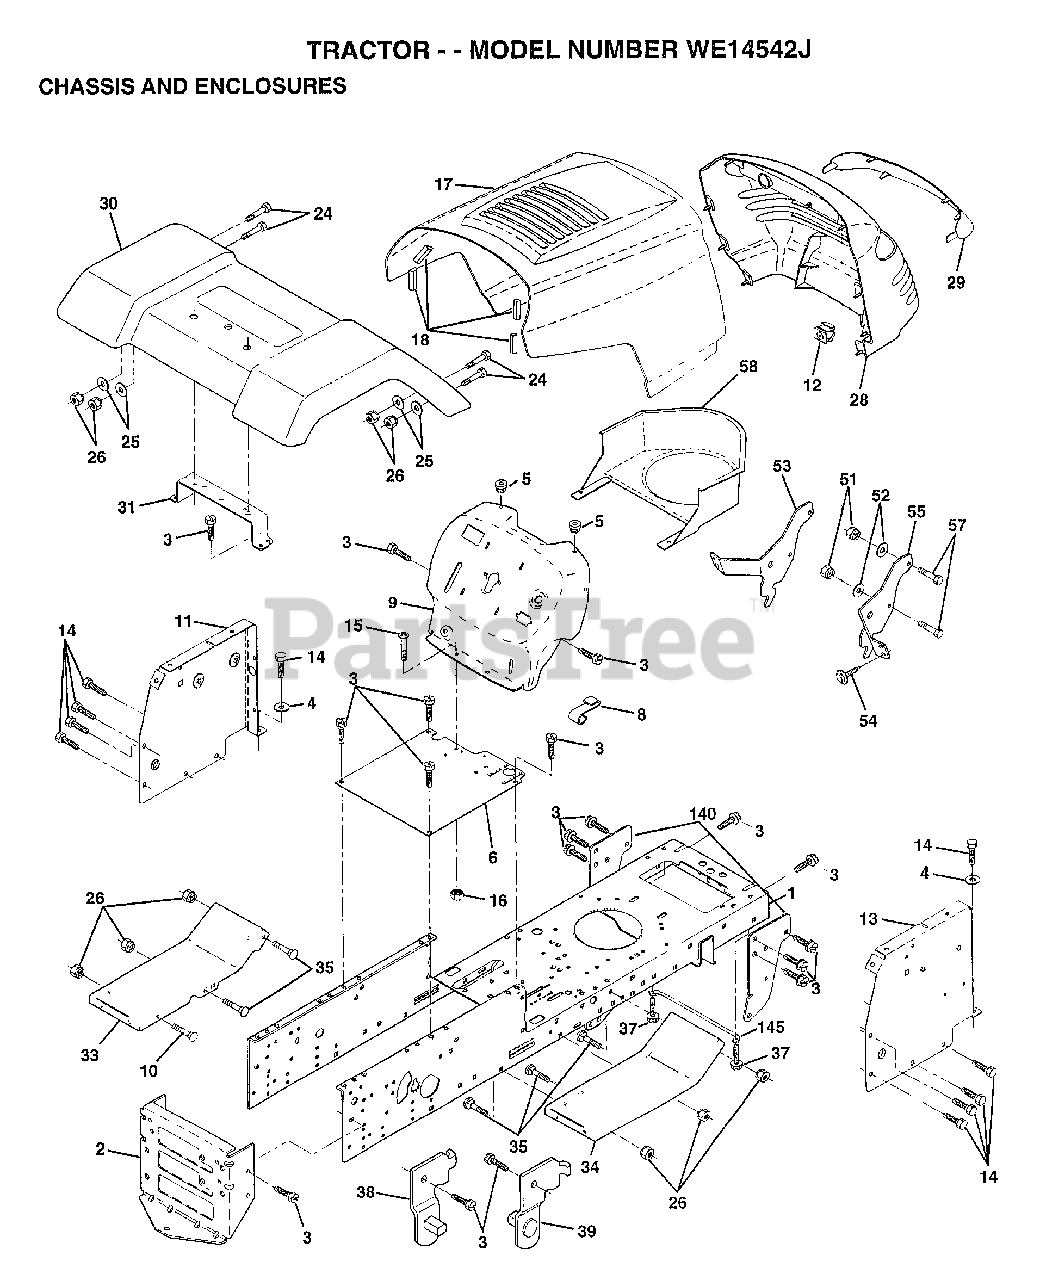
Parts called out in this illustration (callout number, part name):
1	CHASSIS.STAMPING
3	SCREW
4	WASHER
5	BUMPER-HOOD/DASH
6	SADDLE
8	CLIP.RETAINER
9	DASH SILKSCREEN
11	"PANEL-DASH,LH"
12	CLIP.TINNERMAN
13	PANEL.ASM.SLKSCR.DASH.RH
14	SCREW LT
15	SCREW
17	HOOD.STEEL.ASSY
24	BOLT
25	WASHER
26	NUT
28	GRILLE-MS428
29	LENS.GRILLE.PRIVATE LABEL
30	FENDER.PNTL.LT.W/O.SHIFT
31	BRKT FENDER
33	FOOTREST.LH.PERF.
34	FOOTREST.RH.PERF.
35	BOLT
37	SCREW LT
38	BRACKET ASM LH
39	BRACKET ASM RH
51	NUT
52	WASHER
53	BRACKET.GRILLE.LH
54	SCREW.HEX.WS.HD
55	BRACKET.GRILLE.RH
58	AIR DUCT
140	BRKT SUSPENSION
145	"ROD POVOT,CHASSIS"
